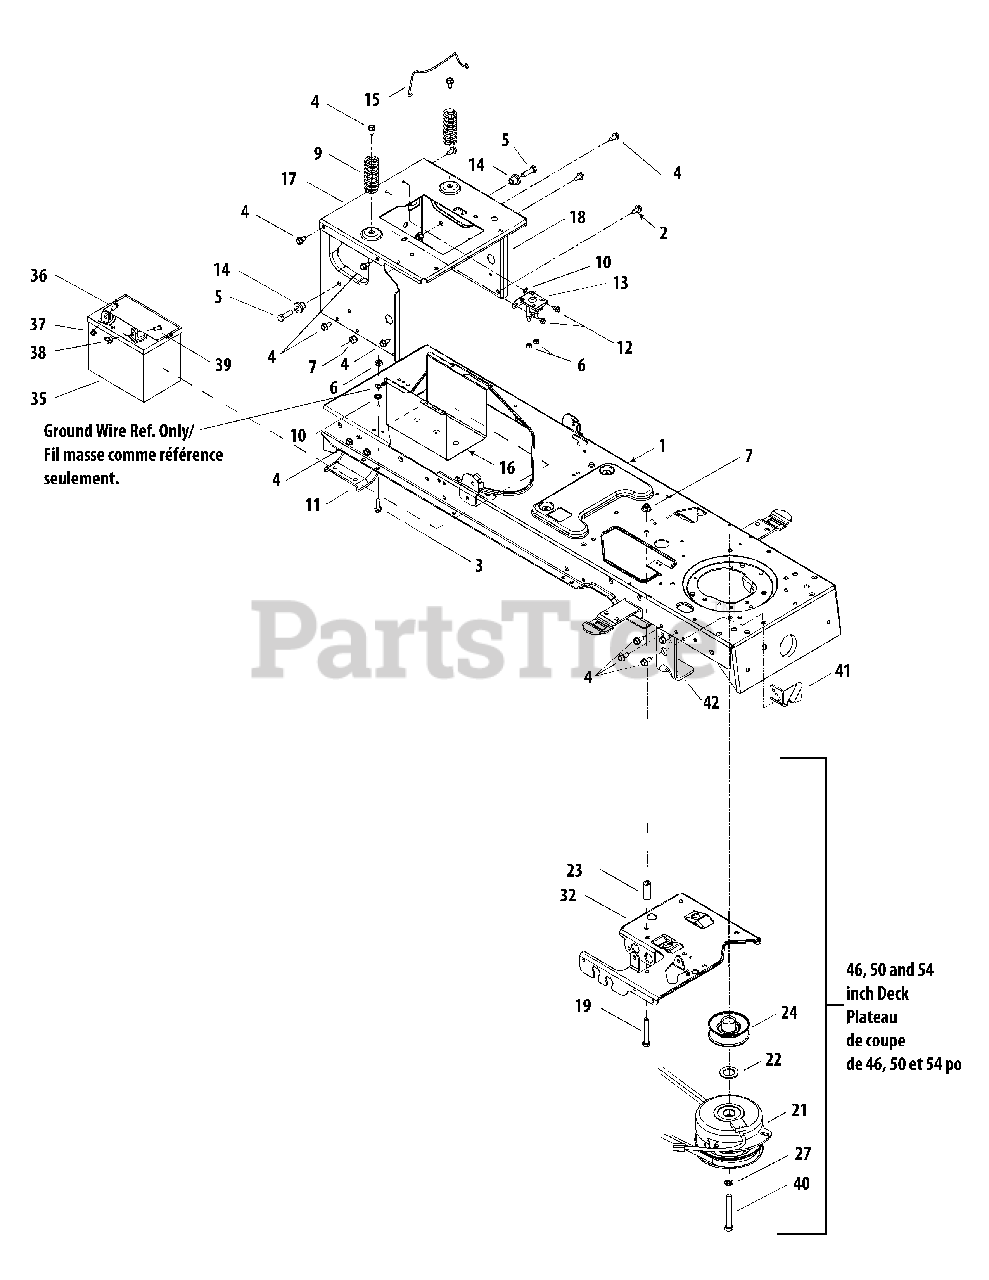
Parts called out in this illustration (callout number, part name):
1	Lower Frame Assembly
2	Hex Wash HD S-Tapp Scr 5/16-18 x .50
3	Thd Forming Scr. 1/4-20 x .75 Lg.
4	S-Tapp Scr 5/16-18 x .75
5	Hex Bolt 3/8-16 x 1.25
6	Hex L-Flanged Nut 1/4-20 Gr. F Ny lon
7	Flange Lock-Nut 3/8-16 Gr. F Ny lon
9	Compression Spring 1.28 x 3.125
10	Ext. L-Washer 1/4 ID
11	Axle Bracket
12	Hex Wash S-Tapp Scr 1/4-20 x .50
13	Solenoid
14	Shoulder Spacer .38 x 1.0 x .70
15	Battery Retainer Rod
17	Frame Seat Bracket
18	Upper Frame (600)
19	Hex Cap Screw, 3/8-16 x 2.25 Gr. 5
21	Electric PTO Clutch 46 & 50" Deck
22	Flat Washer 1.03 ID x 1.64 OD x .095
23	Spacer .385 ID x .635 OD x 1.54
24	Engine Pulley (w/Hydrostatic Models)
27	Lockwasher 7/16 ID
32	Steering Support Bracket
35	Battery 245 CCA (Dry)
36	Hex Flg. Bolt 1/4-10 x .75 Gr. 5
37	Sems Hex Nut 1/4-20
38	Wing Nut 1/4-20 Thd.
39	Shoulder Screw, 1/4-20
40	Hex Hd. Cap Scr. 7/16-20 x 3.5
41	Bracket Clutch (w/ 54" Deck)
42	Bracket - Deck Stop (w/54" Deck)
